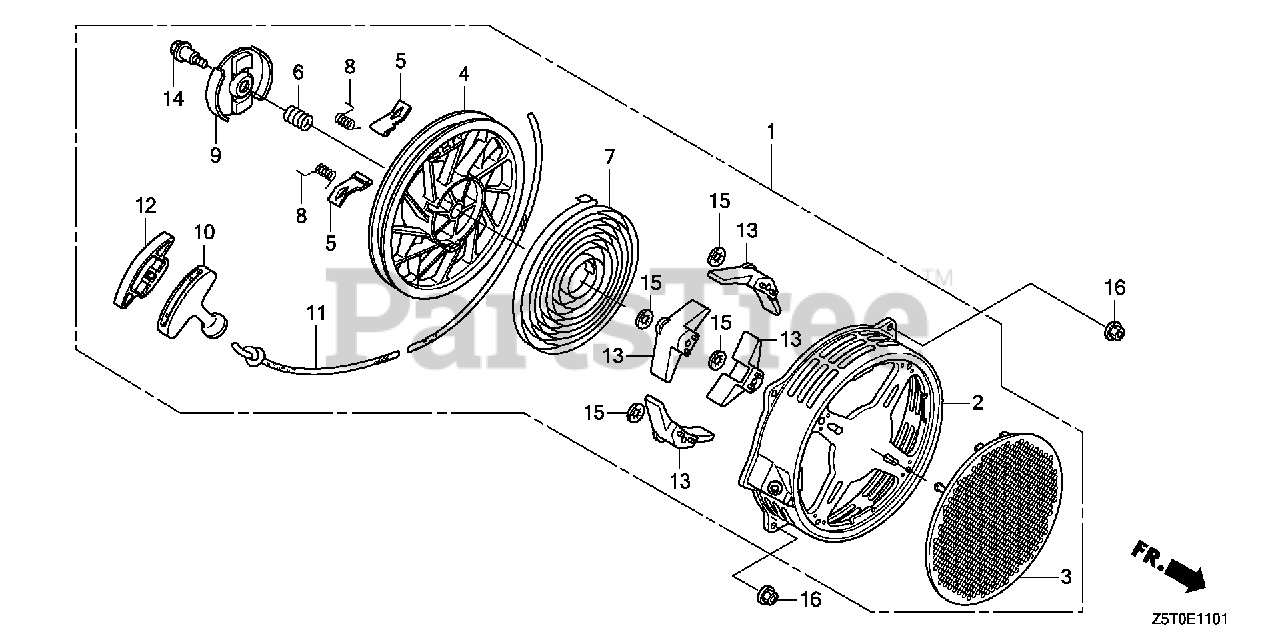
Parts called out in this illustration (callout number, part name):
1	STARTER ASSY. *NH1*
1	STARTER ASSY., RECOIL *R280* (POWER RED)
1	STARTER ASSY., RECOIL *NH1* (COO)(FOR U.S.A.) (BLACK)
2	CASE, RECOIL STARTER *NH1* (BLACK)
2	CASE, RECOIL STARTER *R280* (POWER RED)
3	COVER, RECOIL STARTER
4	PULLEY, RECOIL STARTER
5	RATCHET, STARTER
6	SPRING, FRICTION
7	SPRING, STARTER RETURN
8	SPRING, RATCHET
9	RETAINER, SPRING
10	GRIP, STARTER
11	ROPE, RECOIL STARTER (#6X64") (N/A: USE P/N 08560-ZG921-11)
12	GRIP, REINFORCEMENT
13	COVER, ROPE
14	SCREW, CENTER
16	NUT, FLANGE (6MM)
